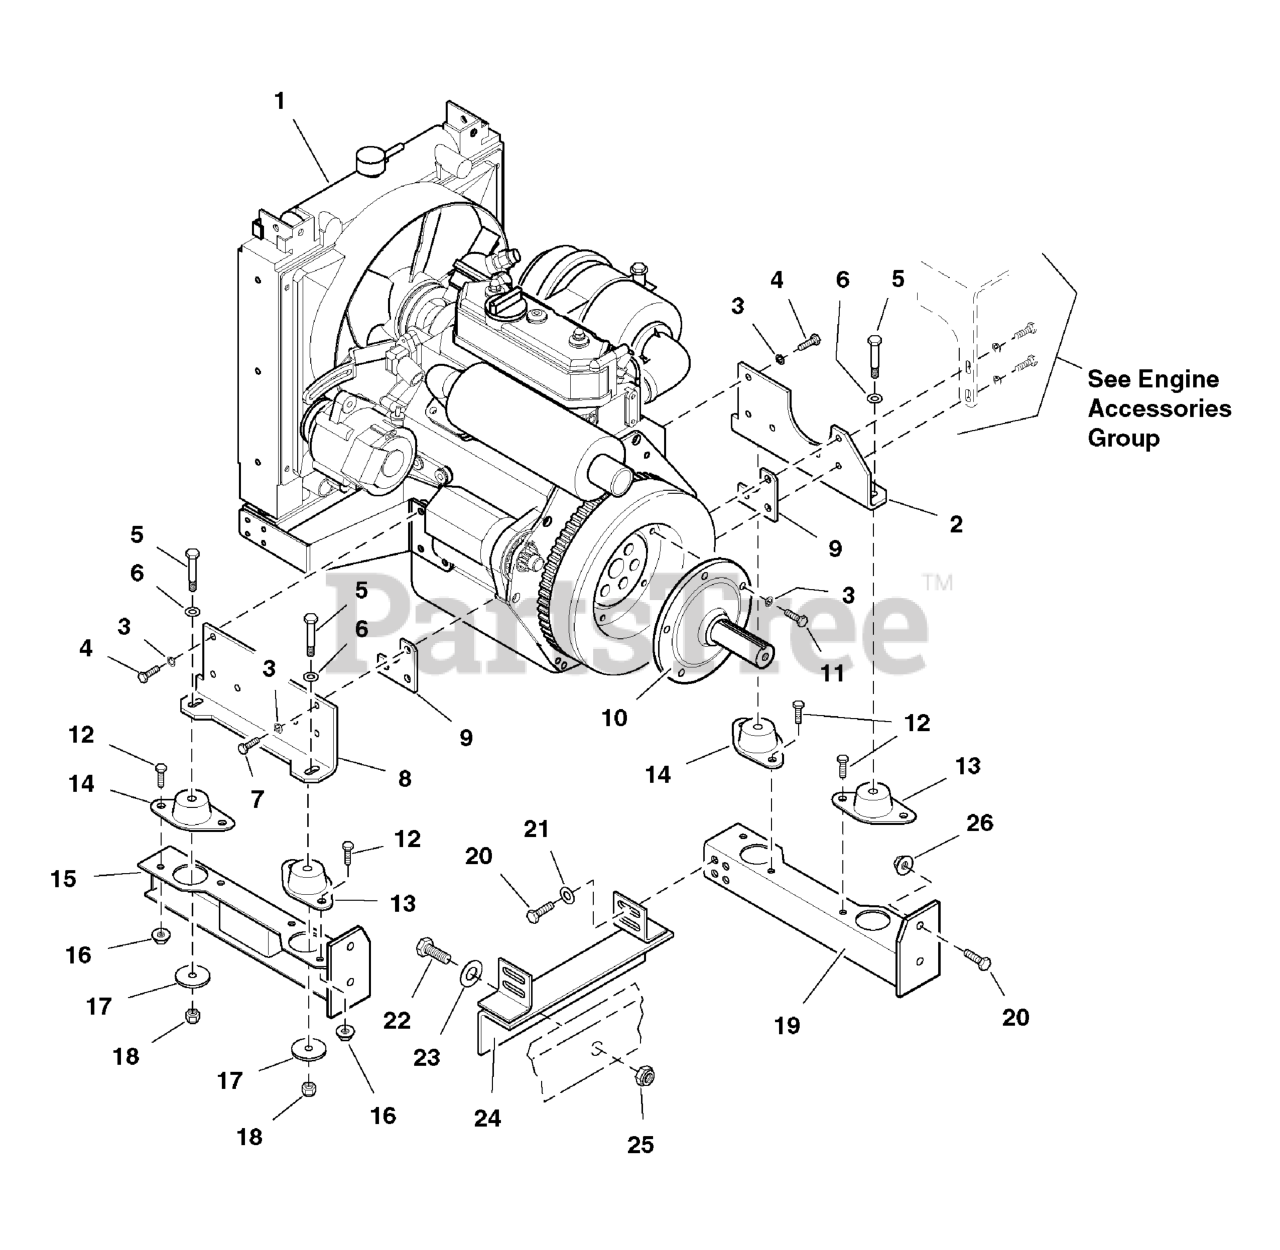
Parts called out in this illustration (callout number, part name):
1	ENGINE, Briggs & Stratton, Gas (Model 950 G)
2	ENGINE MOUNT-RH
3	WASHER, 5/16 LOCK CZ
4	BOLT, M8 x 30MM
5	BOLT, 3/8-16 X 2-1/2" GD5 CZ
6	WASHER, 3/8 SAE
7	BOLT, M8-1.25 X 25MM GR 8.8
8	ENGINE MOUNT-LH
9	SPACER, Engine Mount
10	STUB SHAFT
11	BOLT, M8 x 20MM
12	BOLT, 5/16-18 X 1 GD5 YZ
13	ENGINE MOUNT, Rubber, #215
14	ENGINE MOUNT, Rubber, #150
15	ENGINE MOUNT RAIL-LH
16	NUT, 5/16-18 HEX SERRATED FLANGE (SMALL)
17	WASHER, Iso Mount
18	NUT, 3/8-16 HEX NYLON LOCK
19	ENGINE MOUNT RAIL-RH
20	BOLT, 3/8-16 X 1" GD5 CZ
21	WASHER, 3/8 SAE
22	BOLT, 1/2-20 X 1-1/2, GD5 CZ
23	WASHER, 1/2 SAE
24	MOUNT, Engine
25	NUT, Hex, Nylon Lock, 1/2-20
26	NUT, 3/8-16 Hex Serrated Flange
